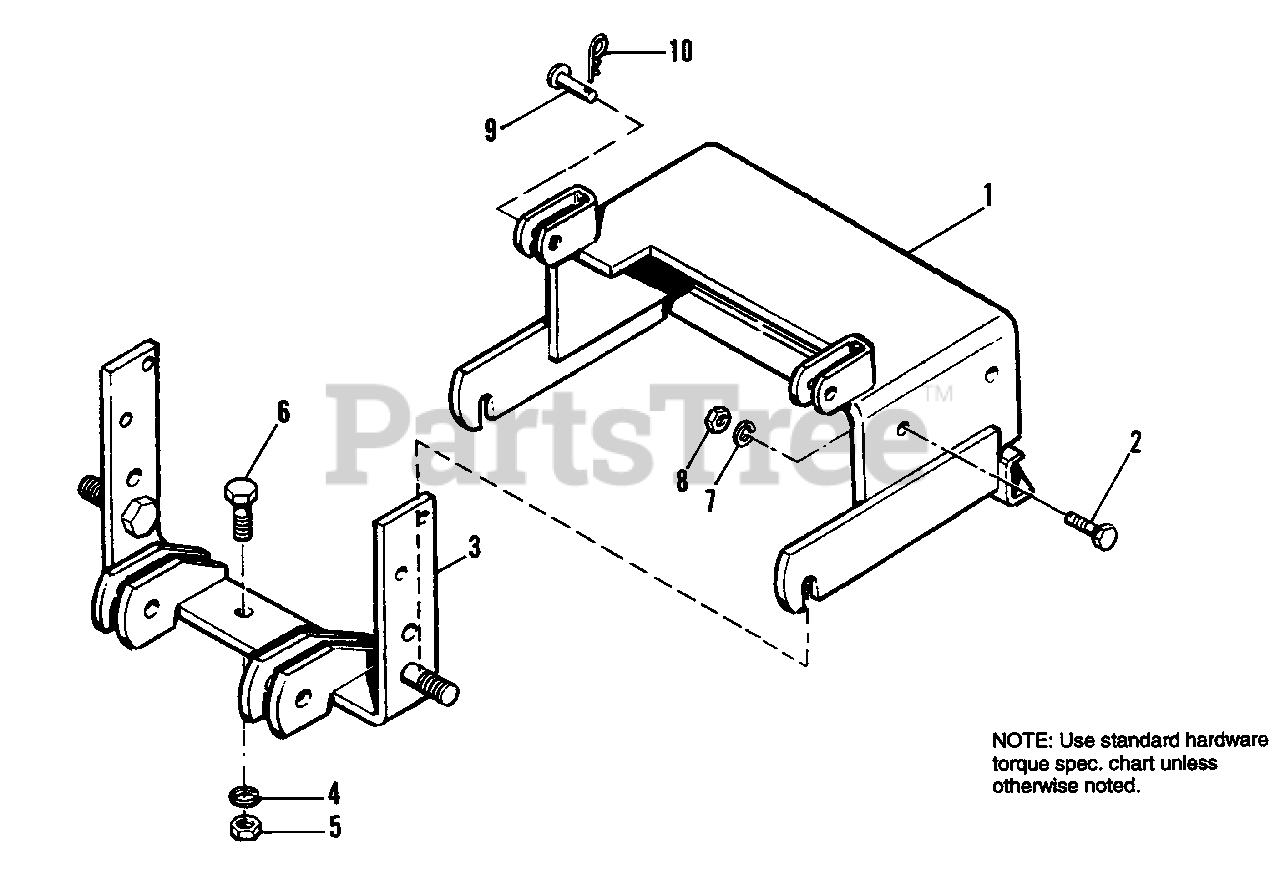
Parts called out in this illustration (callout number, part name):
1	HITCH ASSY.
2	CAPSCREW, Hex Hd., 7/16 x 14 x 1-1/4
3	BRACKET ASSY.
4	WASHER, Lock
5	NUT, Hex, 1/2-13
6	CAPSCREW, Hex Hd., 1/2-13 x 1/4
7	WASHER, Lock, 7/16
8	NUT, Hex, 1/2-13
9	PIN, Clevis
10	PIN, Quick
